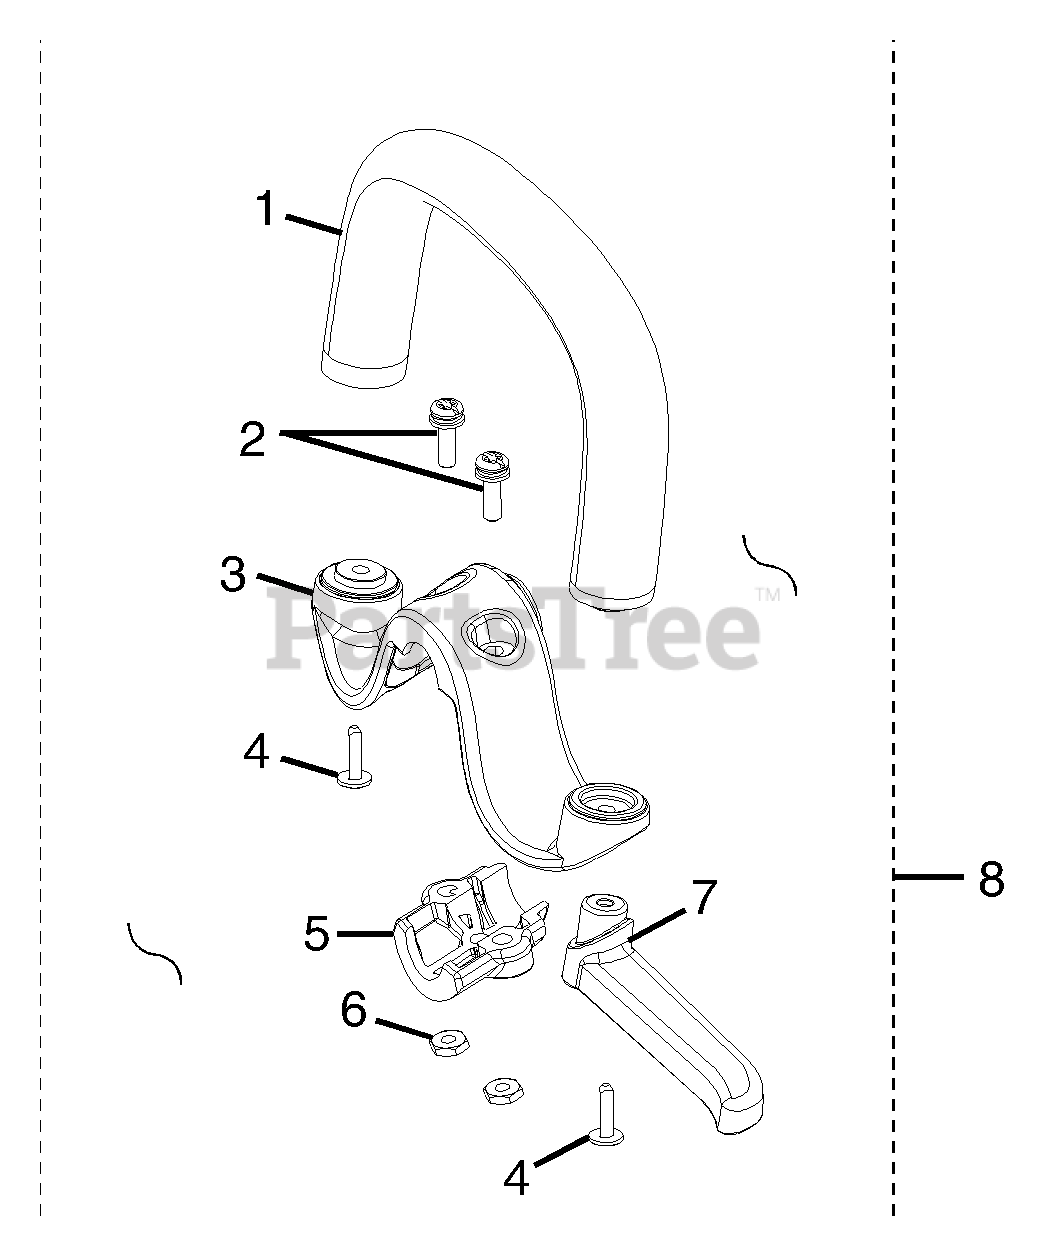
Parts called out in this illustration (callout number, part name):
1	ASSIST HANDLE W/GRIP
2	SCREW (12-24 x 1 SEMS)
3	M CLAMP
6	HEX NUT (12-24)
7	BARRIER BAR
8	ASSIST HANDLE ASSEMBLY
